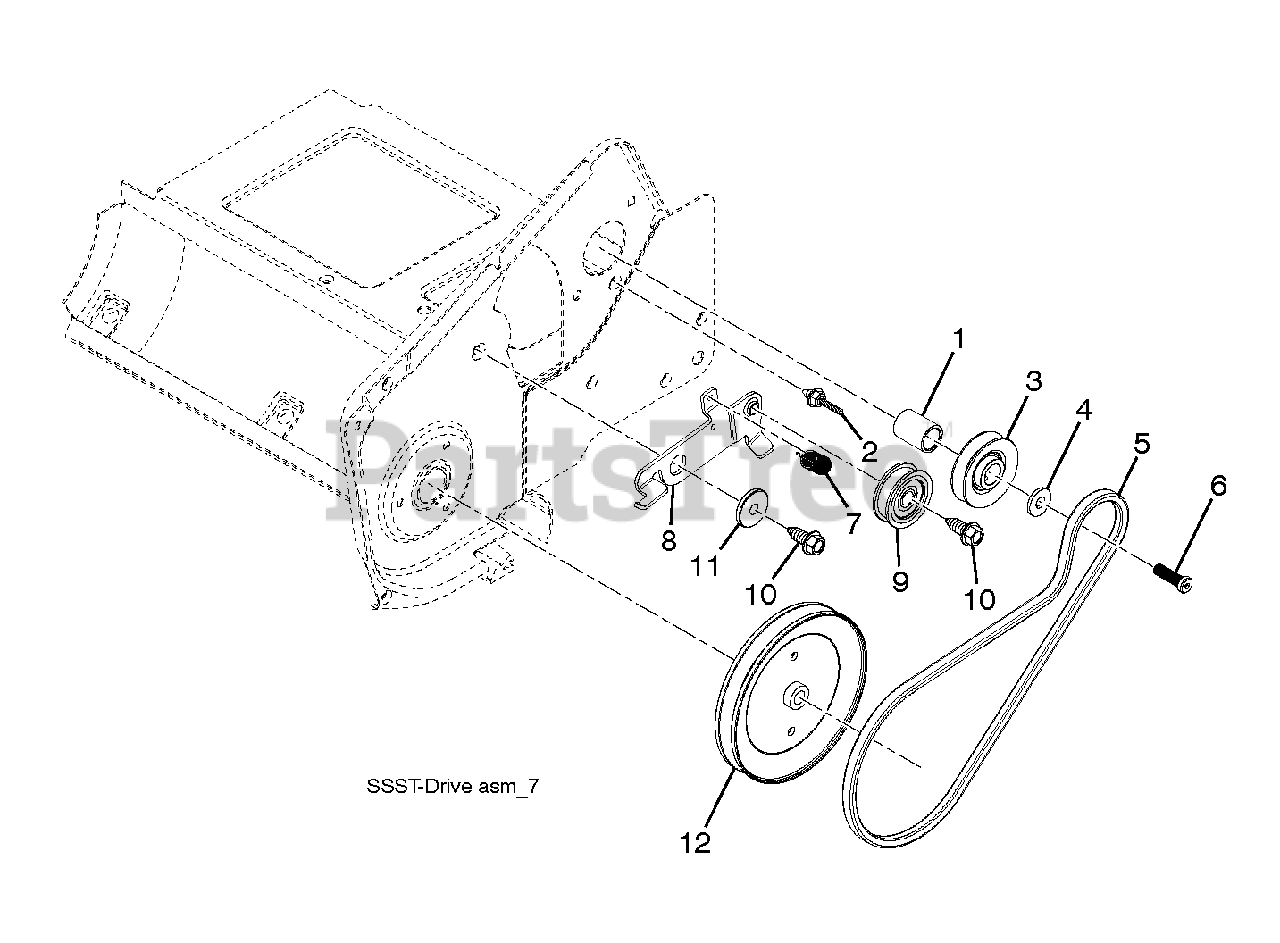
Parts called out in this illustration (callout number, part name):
1	SPACER.ENGINE.CRANK
2	KEEPER.ENGINE.BELT
3	PULLEY.ENG.TRACTION
4	WASHER,HARDEN
5	BELT.4L.1/2X35
6	BOLT, SCKT HD 3/8-24 X 1 .25
7	SPRING.EIDLER.PULLEY.RETURN
8	ARM.IDLER.PNT.MS431
9	IDLER PULLEY
10	SCREW.3/8-16
11	SPACER.RETAINER
12	PULLEY.DRIVEN
